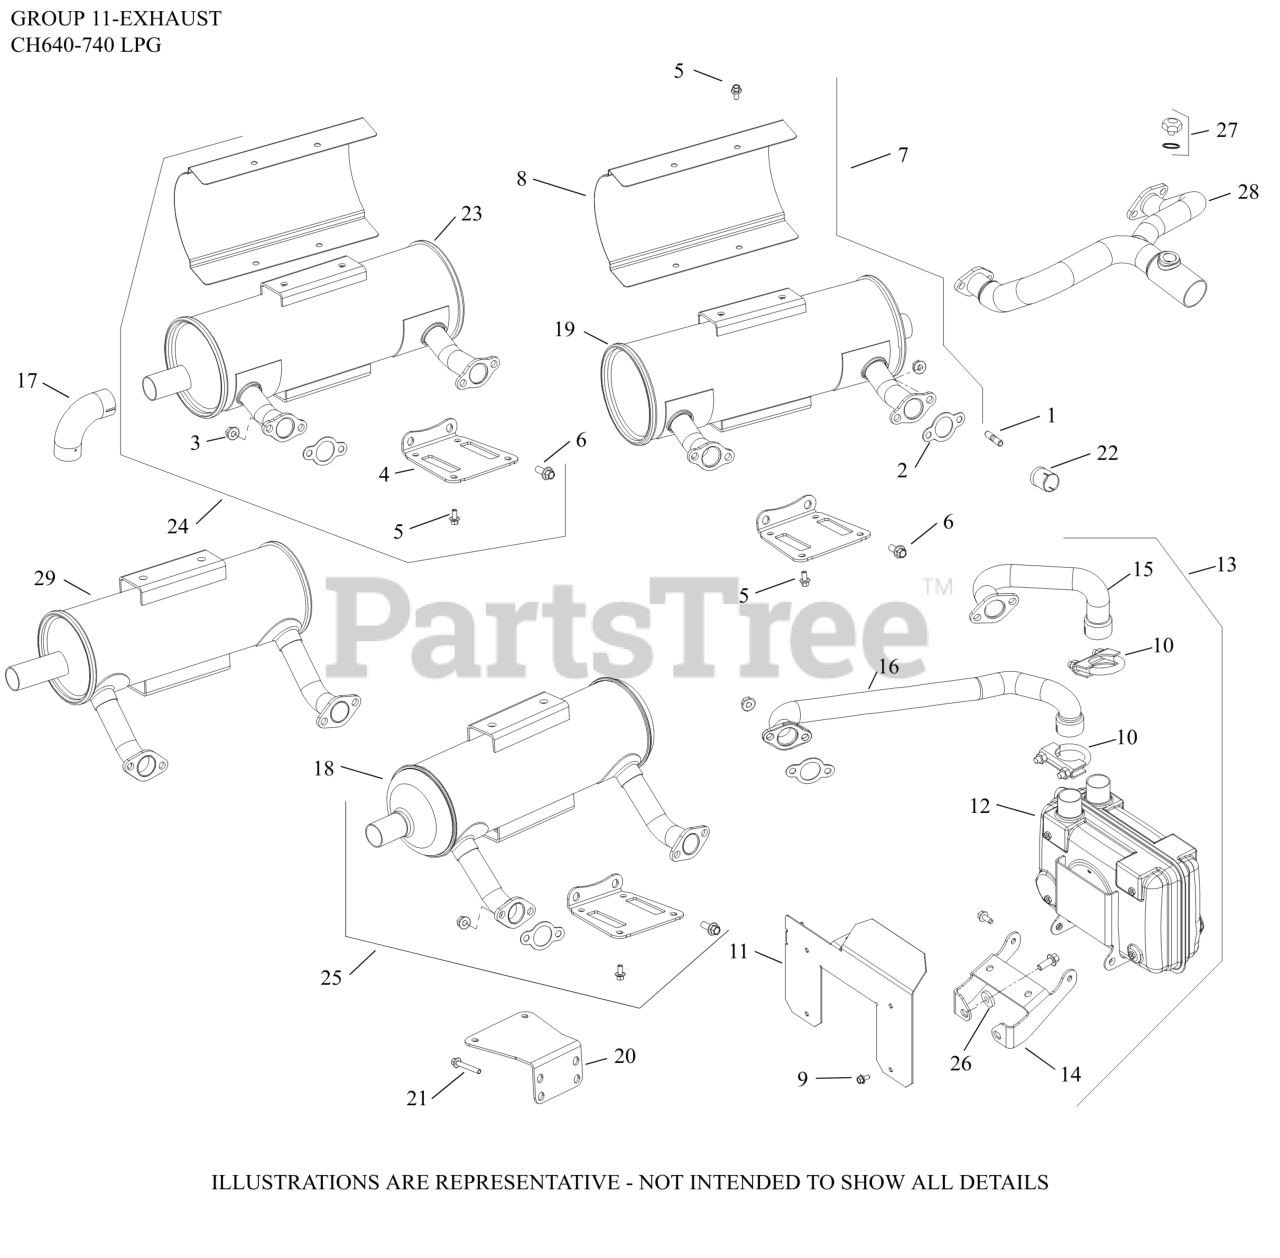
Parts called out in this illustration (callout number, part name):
2	GASKET, EXHAUST
3	NUT, FLG M8X1.25
22	LINER, EXHAUST PORT
